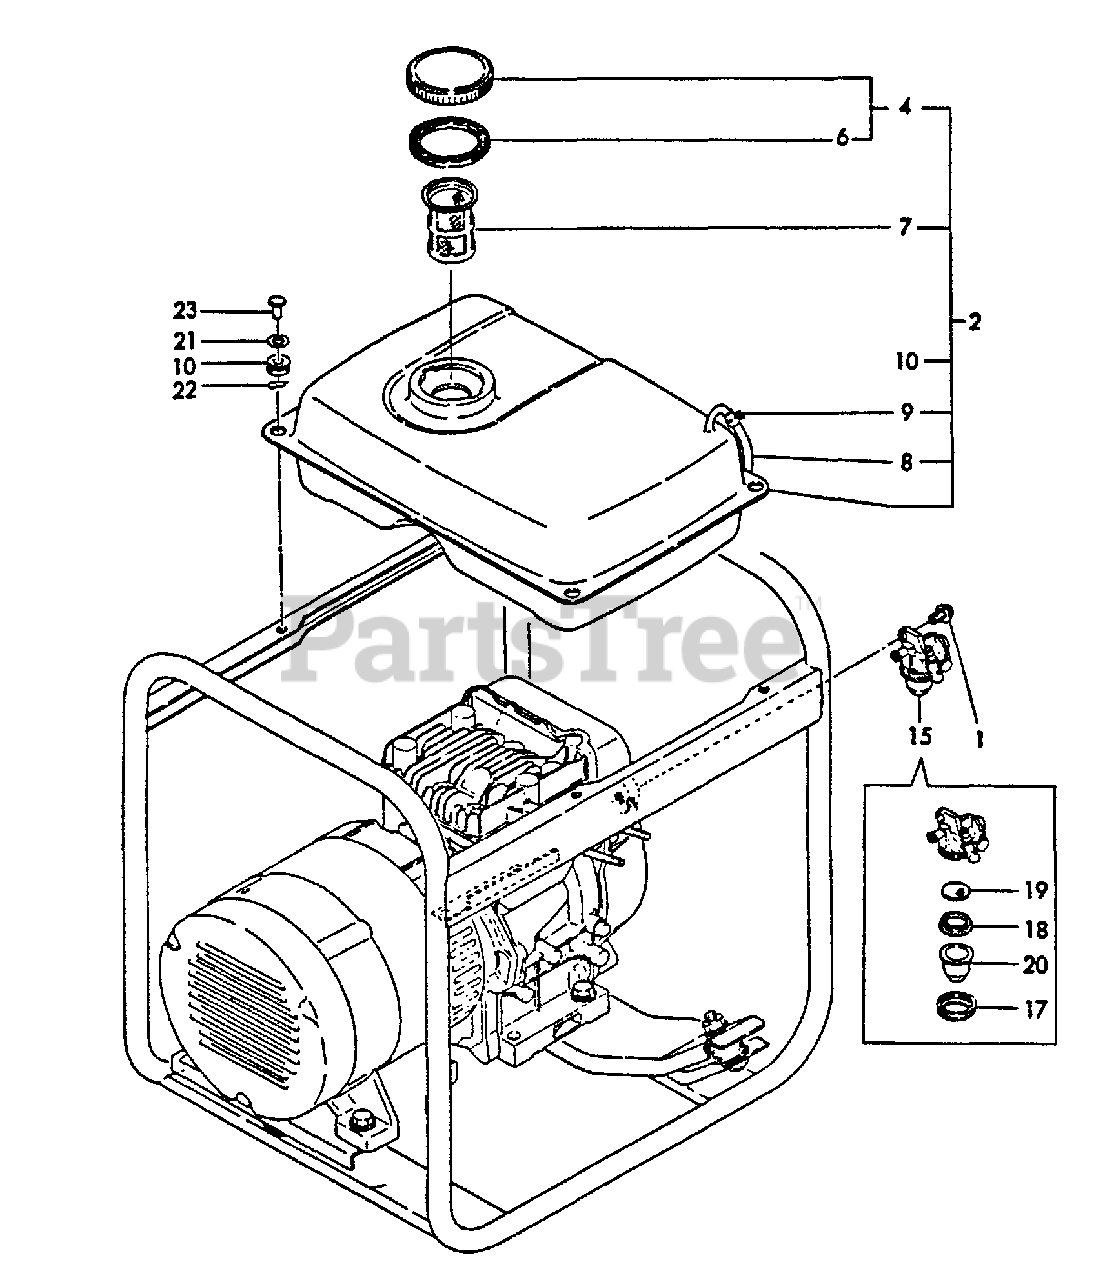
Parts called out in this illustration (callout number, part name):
1	BOLT - 6X8 -- PLATED
2	FUEL TANK ASSY
4	CAP ASSY
6	GASKET
7	STRAINER, FUEL
8	PIPE, FUEL GAUGE
9	CLAMP, HOSE - 9
10	GROMMET
15	FUEL COCK ASSY
17	RETAINER
18	GASKET
19	STRAINER, FUEL
20	BOWL, STRAINER
21	WASHER
22	PIN - 6 -- SNAP
23	PIN - 6X14
